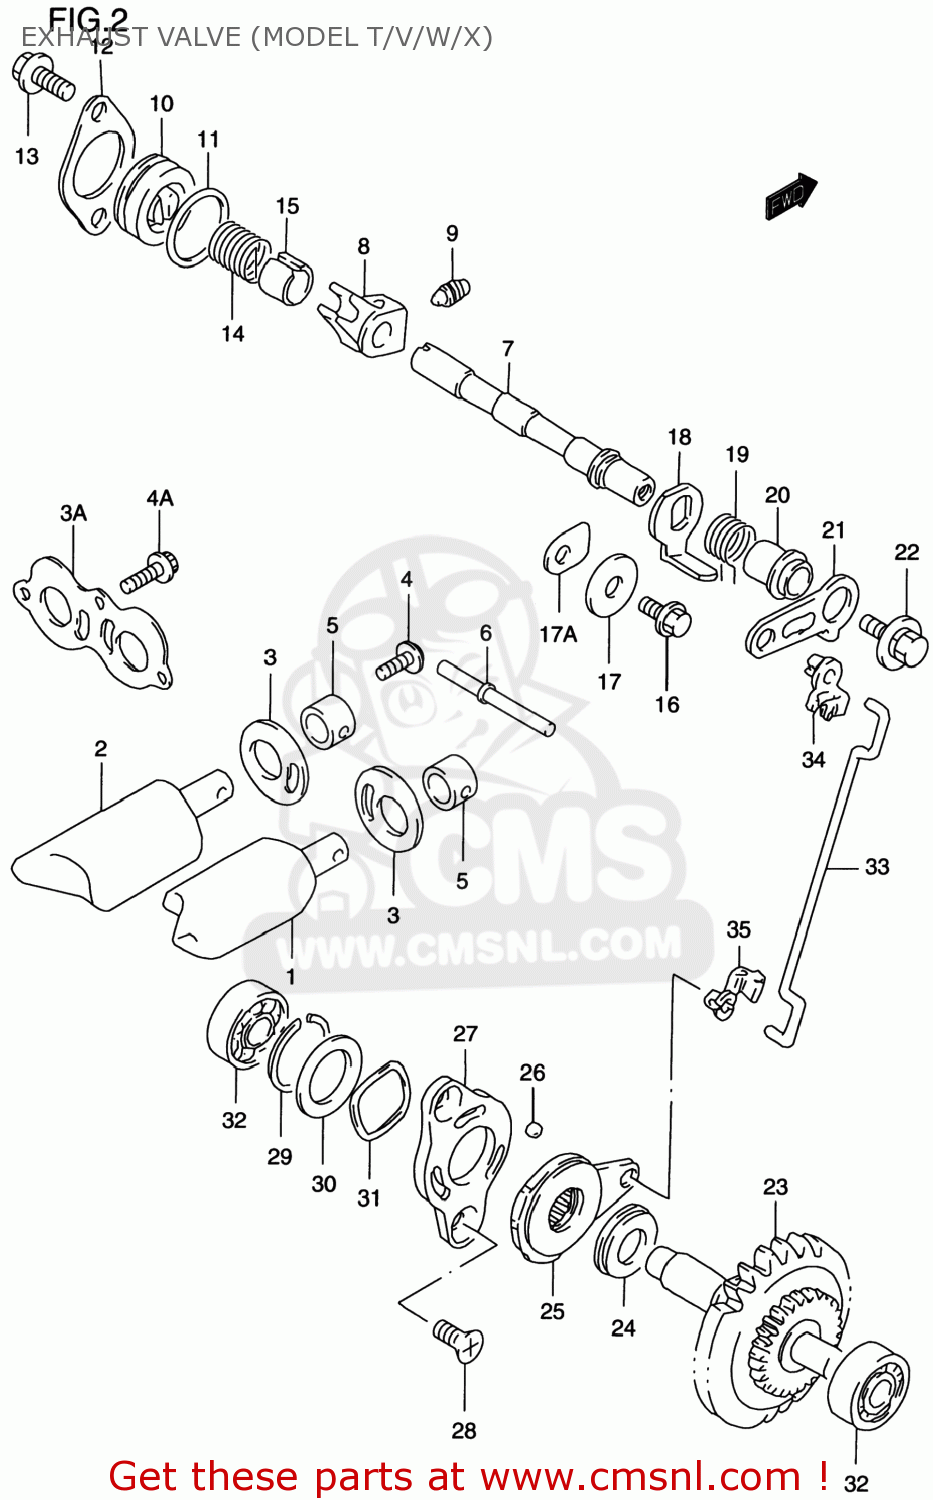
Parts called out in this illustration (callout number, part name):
1	VALVE,EXHAUST,R
2	VALVE,EXHAUST,L
3	PLATE,EXHAUST VALVE
3A	PLATE,EXHAUST VALVE
4	SCREW 5X12
4A	BOLT
5	SPACER,EXHAUST VALVE
6	PIN,EXHAUST VALVE
7	SHAFT,EXHAUST VALVE
8	ARM,EXHAUST VALVE SHAFT
9	SCREW(6X10)
10	CAP,EXHAUST VALVE
11	O RING(D:1.9,ID:22.6)
12	RETAINER,EXHAUST VALVE
13	BOLT
14	SPRING
15	SPACER,EXHAUST VALVE SPRING
16	BOLT
17	WASHER
17A	RETAINER
18	LEVER,EXHAUST VALVE NO.2
19	SPRING
20	SPACER,EXHAUST VALVE
21	LEVER,EXHAUST VALVE NO.1
22	BOLT(5X12)
23	GOVERNOR ASSY,EXHAUST VALVE
24	BEARING(10X22X2.8)
25	ACTUATOR,EXHAUST VALVE
26	BALL
27	STARTER,EXHAUST VALVE ACTUATOR
28	SCREW(5X10)
29	CIRCLIP
30	SHIM(19.1X25X0.3)
31	WASHER
32	BEARING(8X22X7)
33	ROD,EXHAUST VALVE
34	BUSH,EXHAUST VALVE ROD NO.1
35	BUSH,EXHAUST VALVE ROD NO.2
